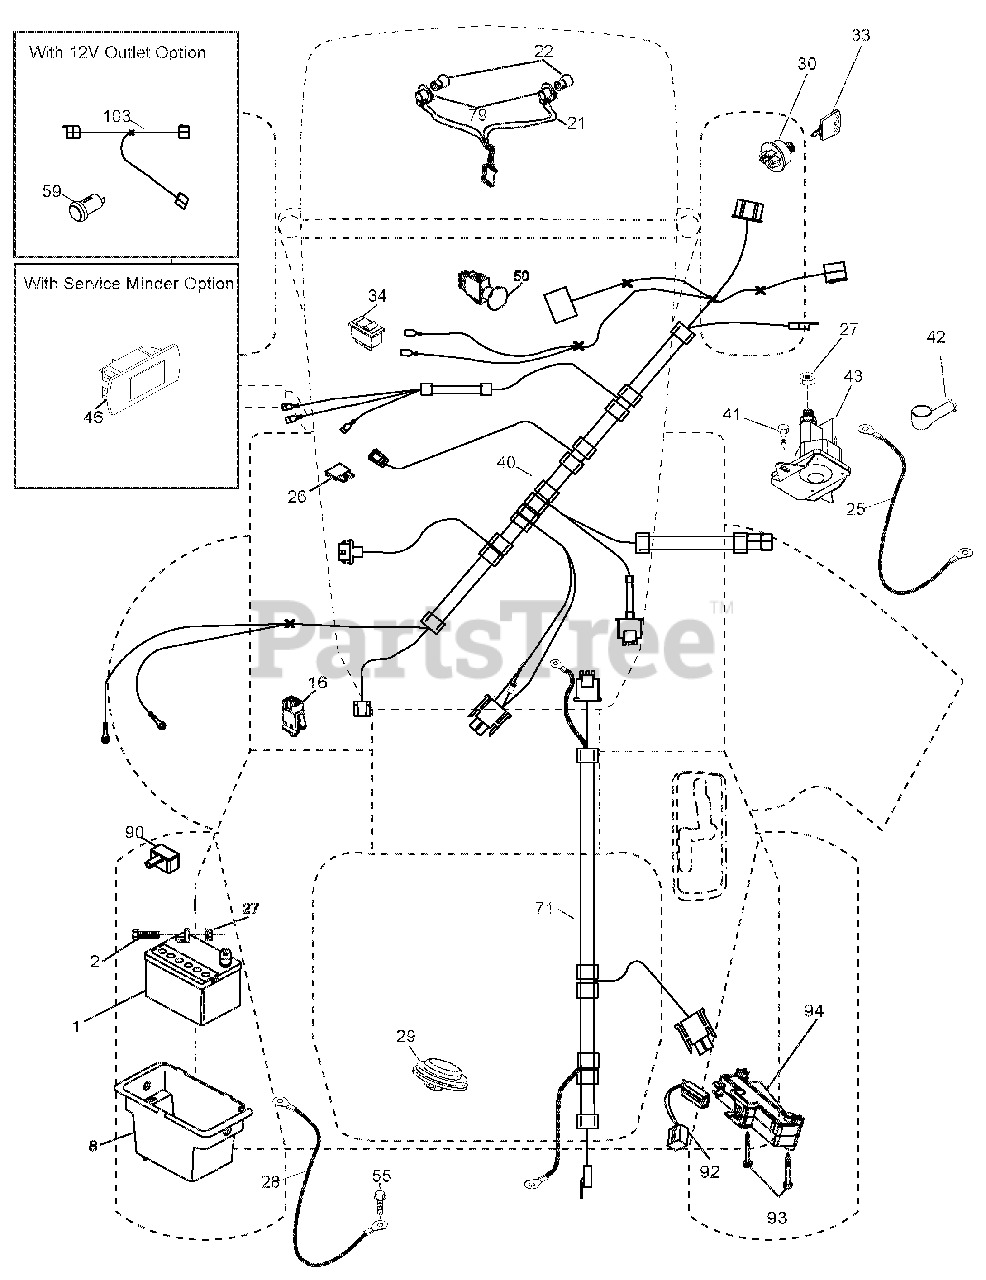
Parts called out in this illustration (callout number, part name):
1	BATTERY.12.VOLT.28.AMP.WET
2	BOLT.HEX.HD.1/4-20UNC X 3/4
8	BOX.BATTERY.MNT.REAR.LT.TEX.BL
16	SWITCH.INTERLOCK.NONO.GRAY
21	HARNESS ASM.LIGHT.22"(4152J)
22	BULB.LIGHT.#1156
25	CABLE STARTER 6 G4. BL/RED14.5
26	FUSE.20 AMP.
27	Nut, Keps Hex 1/4-20 unc
28	CABLE.BLACK.22"REAR BATT.TEX
29	SWITCH.SEAT.DELTA.OPC.9LB.
30	SWITCH.IGN.DLTA.P-IN.ROS
33	KEY/CHAIN.BLISTER PACK.GEN.USA
34	SWITCH.LIGHT/RESET.B/B/RED.
40	HARNESS.IGN.DASH.HUSQ/PRED.
41	Screw 1/4-20 x 1/2
42	COVER.TERMINAL.RED
43	SOLENOID.W/BRASS PLUNGER.2005
50	SWITCH.PTO.8 TERMINAL.BLACK
55	SCREW.5/16-18X3/4.SMGML.TAP/R
71	HARNESS.IGN.CHASS.TEX.REAR.BAT
79	SOCKET ASM.BULB.TWISTLOCK
90	COVER TERMINAL BATTERY FR. TEX
92	HARNESS.PIGTAIL.CONSLE.ROS.MLK
93	SCREW.PLASTITE.10-14 X 2.0
94	MODUAL REVERSE ROS
